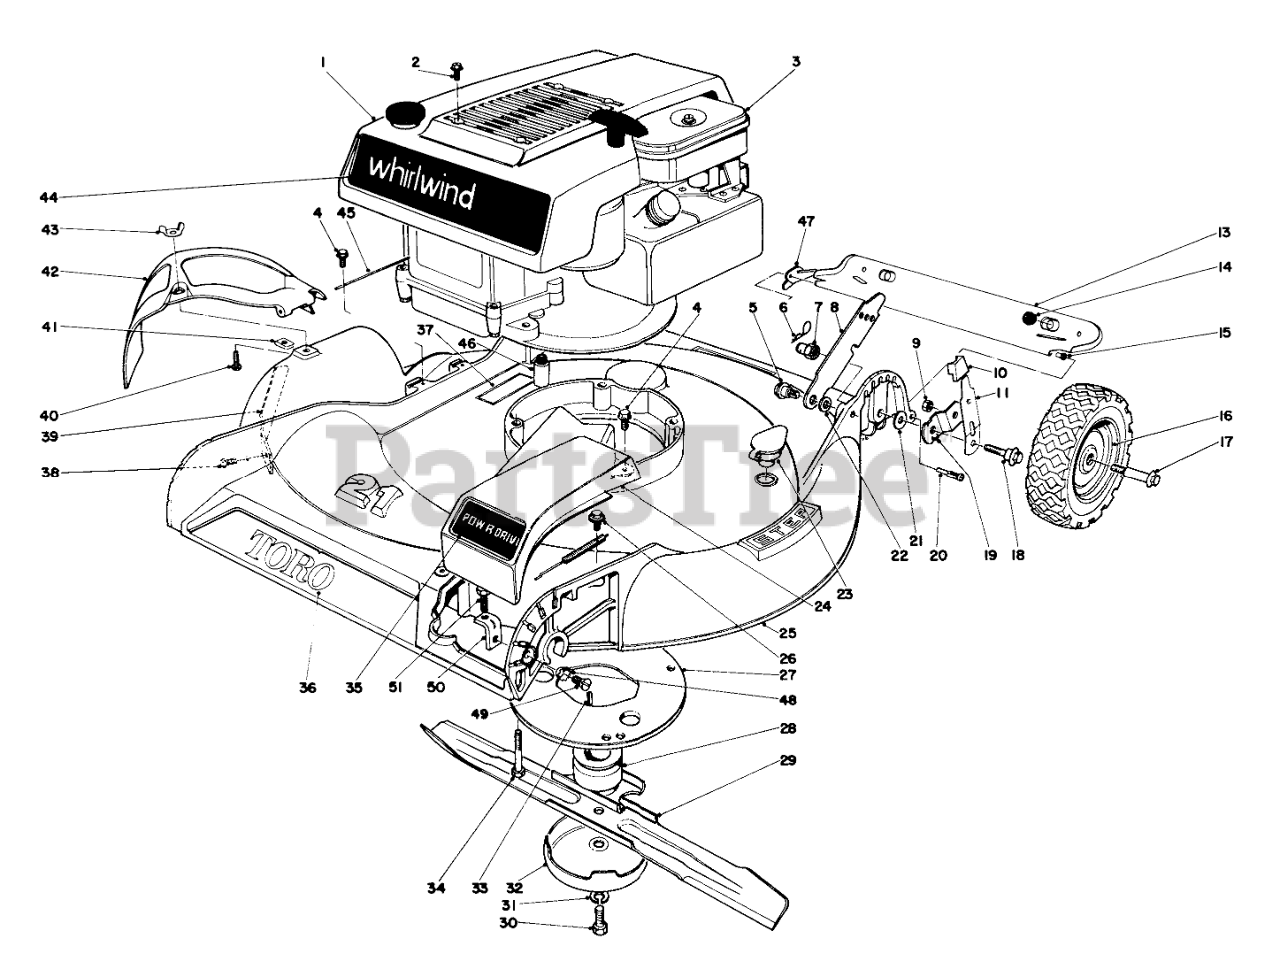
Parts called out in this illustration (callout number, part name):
1	Shroud
2	8X1/2 SELF TAP SCREW
3	Engine
4	SCREW
5	SCREW-SHOULDER
6	PIN-COTTER, HAIR
7	HANDLE PIVOT NUT
8	Latch
9	Nut
10	Arm Knob
11	Spring Arm
13	Rear Safety Shield (Incl. Ref. #14 & 15)
14	SKID BUTTON
15	SAFTEY SHIELD BUSHING
16	Rear Wheel w/Tire (Incl. Ref. #12)
18	PIVOT SCREW
19	PIVOT ARM PLATED
20	SAFTEY SHIELD SCREW
21	WASHER-PIVOT
22	SPACER
23	WASHOUT PLUG
24	Guard, Belt
25	Housing
26	SCREW-HWHTF
27	Grass Guard
28	Blade Retainer
29	Blade
30	SPECIAL SCREW
31	WASHER-LOCK
32	AntiScalp Cup
33	Key Square
34	3/8-16 X 2-3/4 CAPSCR
35	Decal Power Drive
36	Decal Toro
37	Decal
38	SCREW-HWH
39	Bar Safety
41	NUT-SPEED
42	Deflector
43	NUT-WING SPECL
44	Decal Whirlwind
45	HINGE PIN
46	OIL DRAIN EXTENSION
47	Restraint R.H.
48	Lockwasher
50	ADJ BRACKET
51	SCREW-HH
